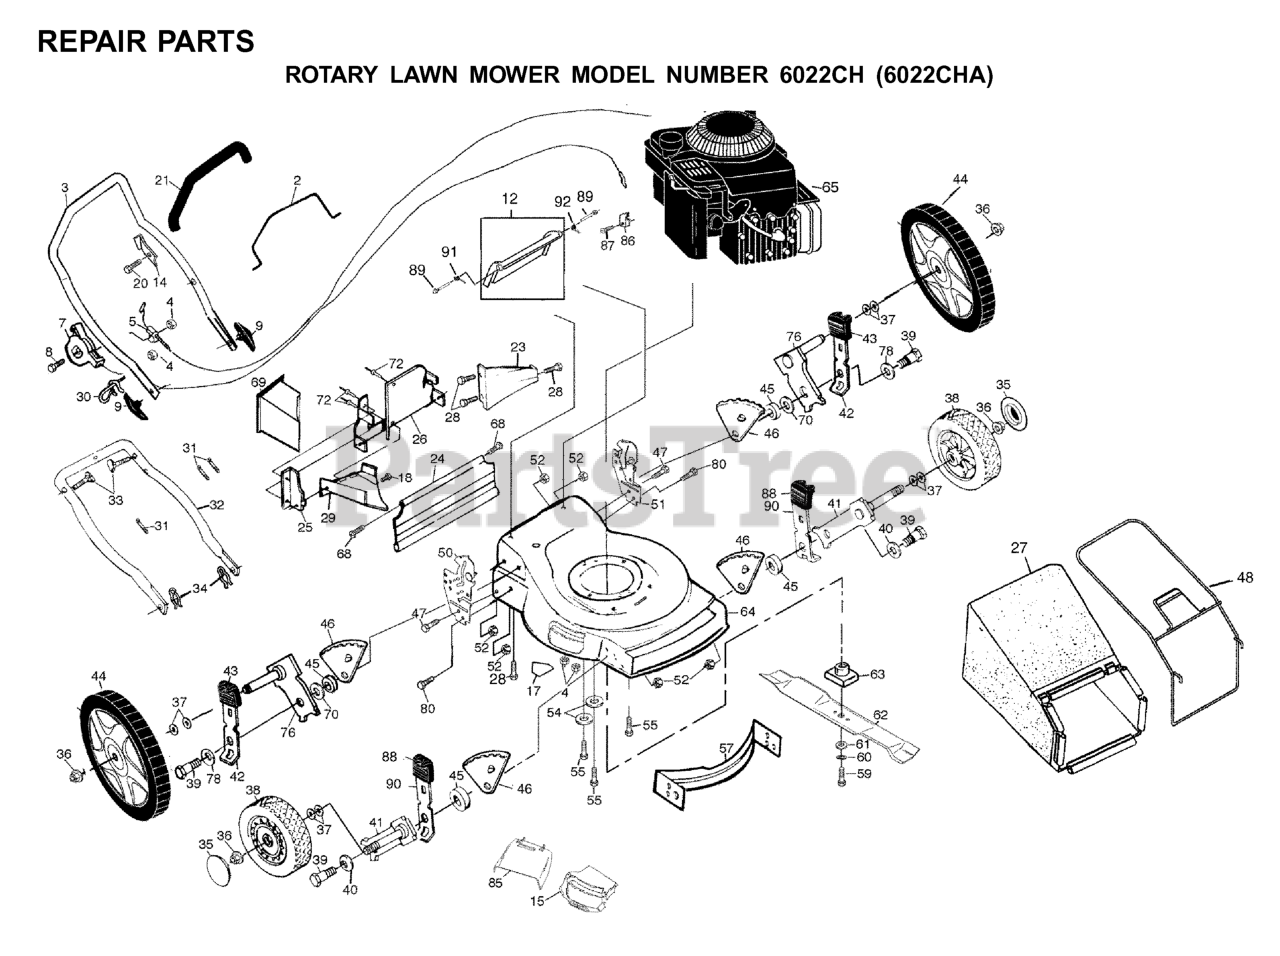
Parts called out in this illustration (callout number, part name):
2	CONTROL BAR
3	HANDLE, UPPER DLX COMF. (GRIP)
4	NUT
5	CABLE.MZR.51.RT.SP./PU.
7	THROTTLE CONTROL
8	SCREW 1/4-20 X 2.12
9	HANDLE KNOB
12	REAR DOOR KIT
14	BRACKET UPSTOP
17	DECAL HYT
18	SCREW.HXTAP.10-24
20	TAPPING SCREW
21	GRIP.HANDLE.FOAM
23	REAR BAFFLE
24	REAR SKIRT
25	SIDE BAFFLE
26	BACK PLATE
29	DISCHARGE BAFFLE
30	ROPE GUIDE
31	TIE GUIDE
32	LOWER HANDLE
33	HANDLE BOLT
34	HAIRPIN COTTER
35	CAP.HUB.BLACK.WALK
36	HEX FLANGE LOCKNT
37	WAVE WASHER
38	WHEEL.8X2.PR.LP.RAD.GREY
39	BOLT
40	WASHER.BELLEVILLE (3 2 LB)
41	AXLE, REAR
44	WHEEL.14X2.PR.SP.RAD.GY
45	RP SPACER HT ADJ
46	WHEEL ADJ BRKT
47	SELF-TAPPING SCREW 5/16-18X3/4
48	CATCHER FRAME
52	LOCKNUT PM
54	WASHER.ENGINE.BZP
55	BOLT 3/8-16X1-1/8
59	SCREW, HEX HD 3/8-24 X 1-3/8
60	LOCKWASHER
61	WASHER,HARDEN
63	BLADE ADAPTOR
68	HINGE SCREW
69	PLUG.MULCH.22RD
70	WASHER.FLAT.1/2
72	RIVET BLIND
86	CABLE CLAMP(ENGINE)
87	SCREW.HEX.HEAD.WASHER.10-16
89	DOOR BOLT
90	SELECTOR SPRING
91	DOOR SPRING RH
92	DOOR SPRING LH
